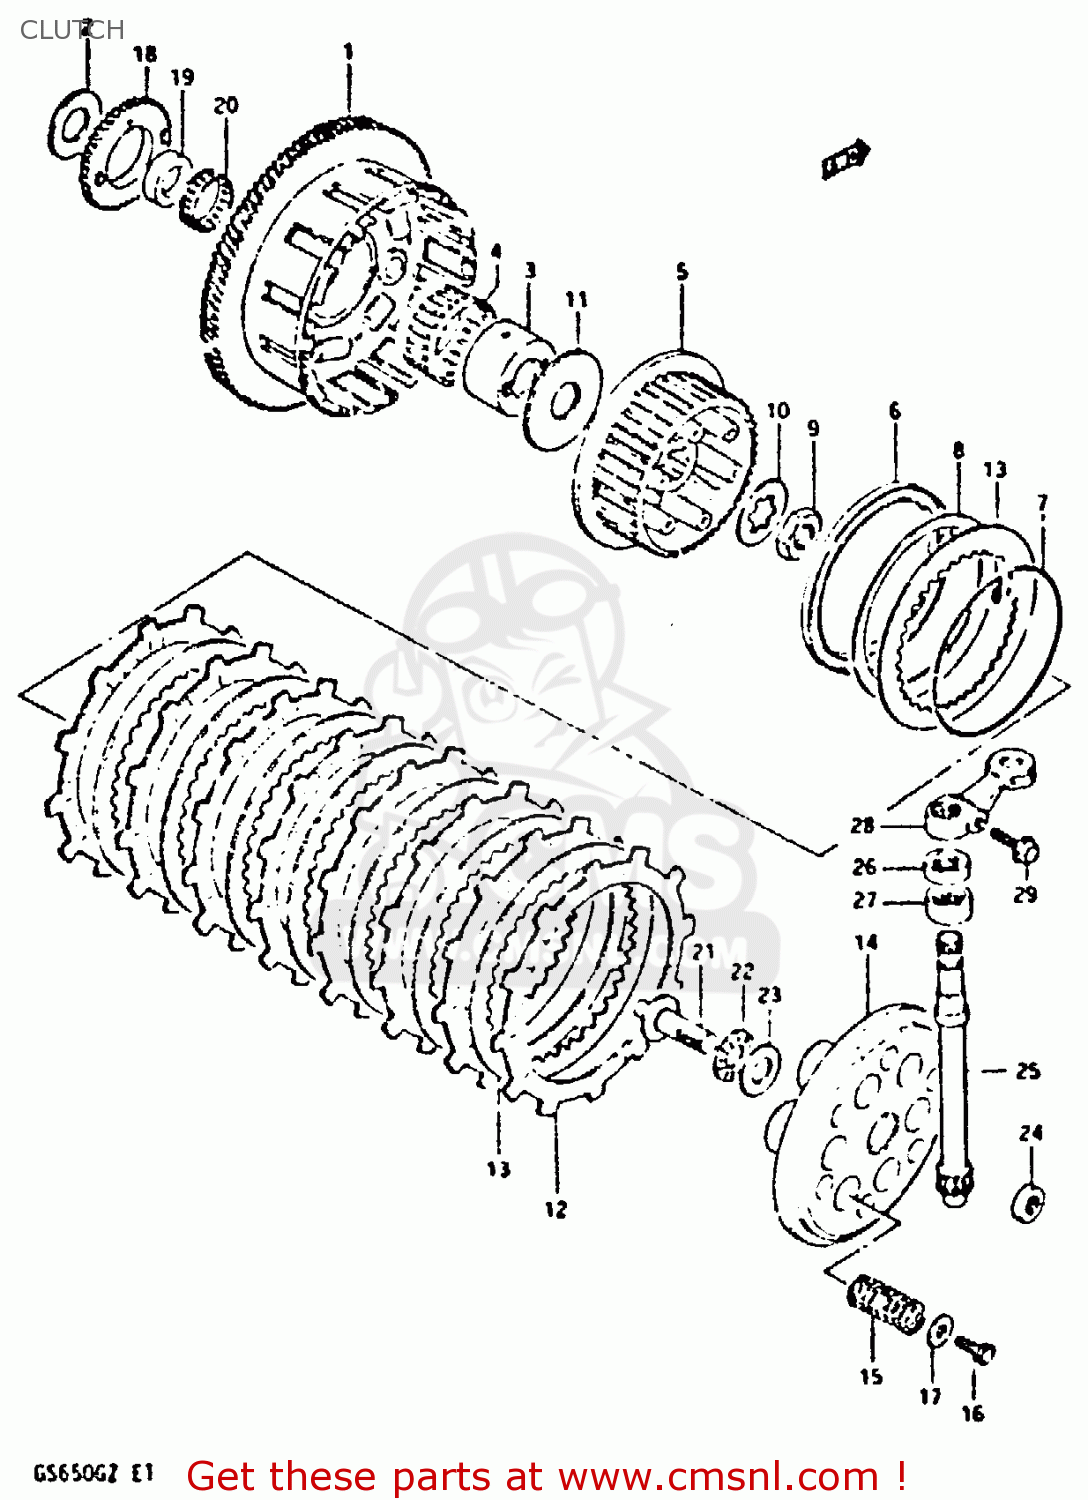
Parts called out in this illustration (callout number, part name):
1	GEAR ASSEMBLY,PRIMARY DRIVE
2	WASHER
3	SPACER
4	BEARING
5	HUB,CLUTCH SLEEVE
6	SEAT,WAVE WASHER
7	RING,STOPPER
8	WASHER
9	NUT
10	WASHER,LOCK
11	WASHER(25X66X3.5)
12	PLATE,CLUTCH DRIVE (MCA)
13	PLATE,CLUTCH DRIVEN(T:2.0) (NAS)
14	DISC,CLUTCH PRESSURE
15	SPRING
16	BOLT, UPPER
17	WASHER
18	GEAR,OIL PUMP DRIVE
19	SPACER,OIL PUMP DRIVE GEAR
20	BEARING(36X40X10)
21	RACK,CLUTCH RELEASE
22	BEARING(15X28X2)
23	WASHER
24	SEAL,OIL(10X16X5)
25	PINION,CLUTCH RELEASE
26	OIL SEAL
27	BEARING(15X22X12)
28	ARM,CLUTCH RELEASE
29	BOLT,REAR
